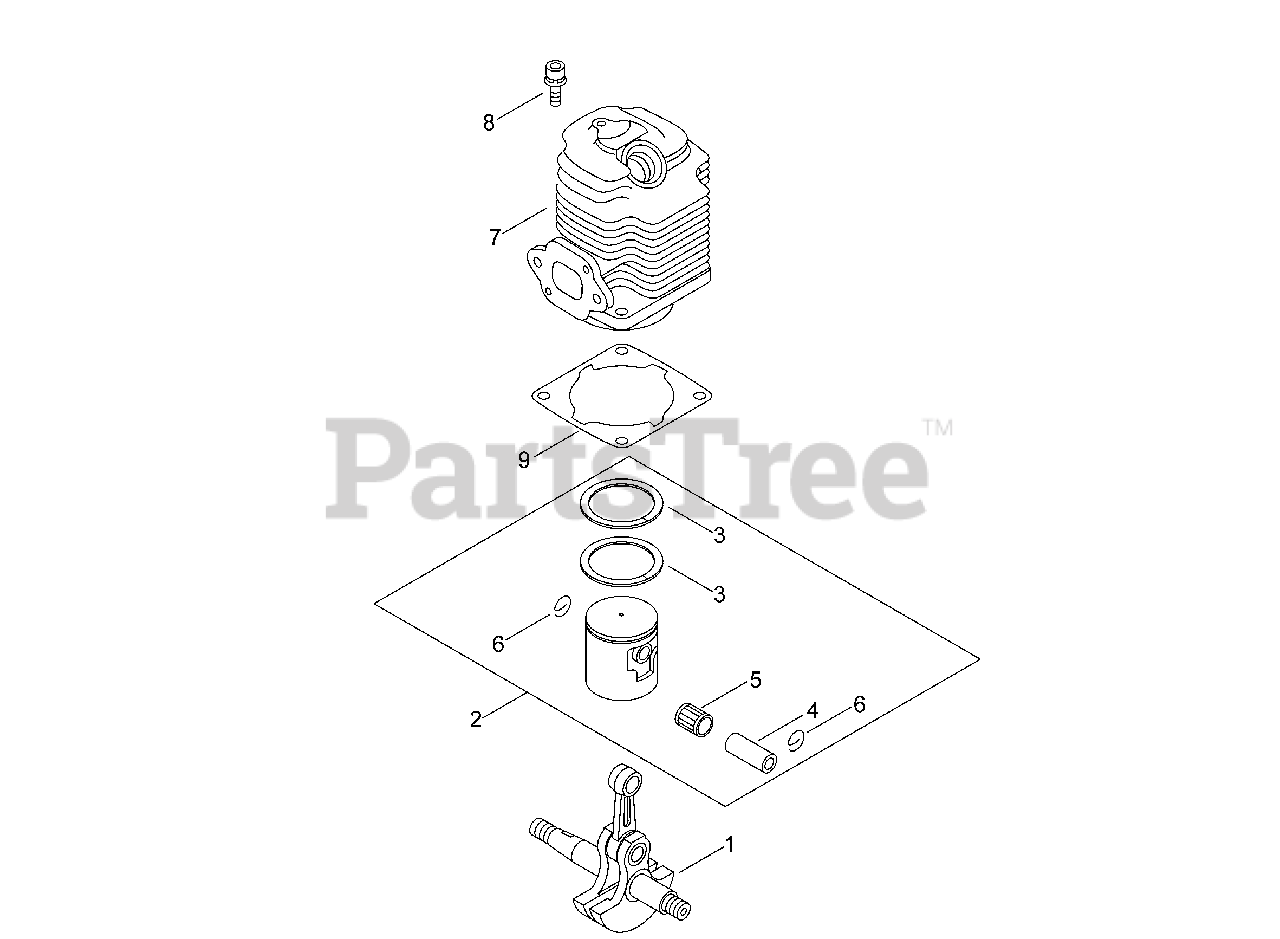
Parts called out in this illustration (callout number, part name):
1	CRANKSHAFT ASSY
2	PISTON KIT
3	RING, PISTON
4	PIN, PISTON
5	BEARING, NEEDLE
6	RING, SNAP Ø10
7	CYLINDER
8	BOLT 5×22
9	GASKET, CYLINDER
